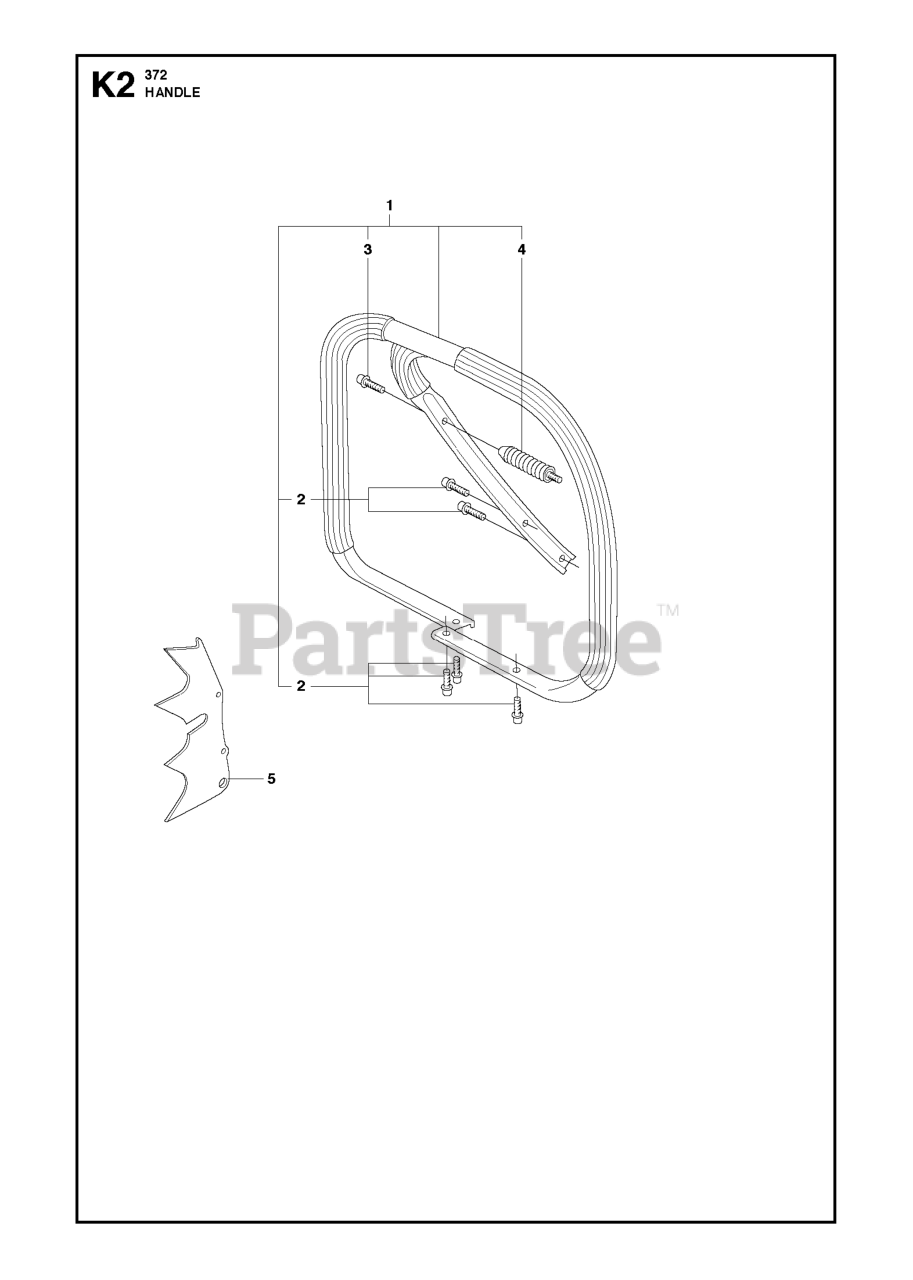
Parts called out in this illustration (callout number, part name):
1	HANDLE, HTD WRAP 372
1	FRONT HANDLE/WRAP
2	SCREW
4	ANTIVIBE MOUNT
5	FELLING DOG
